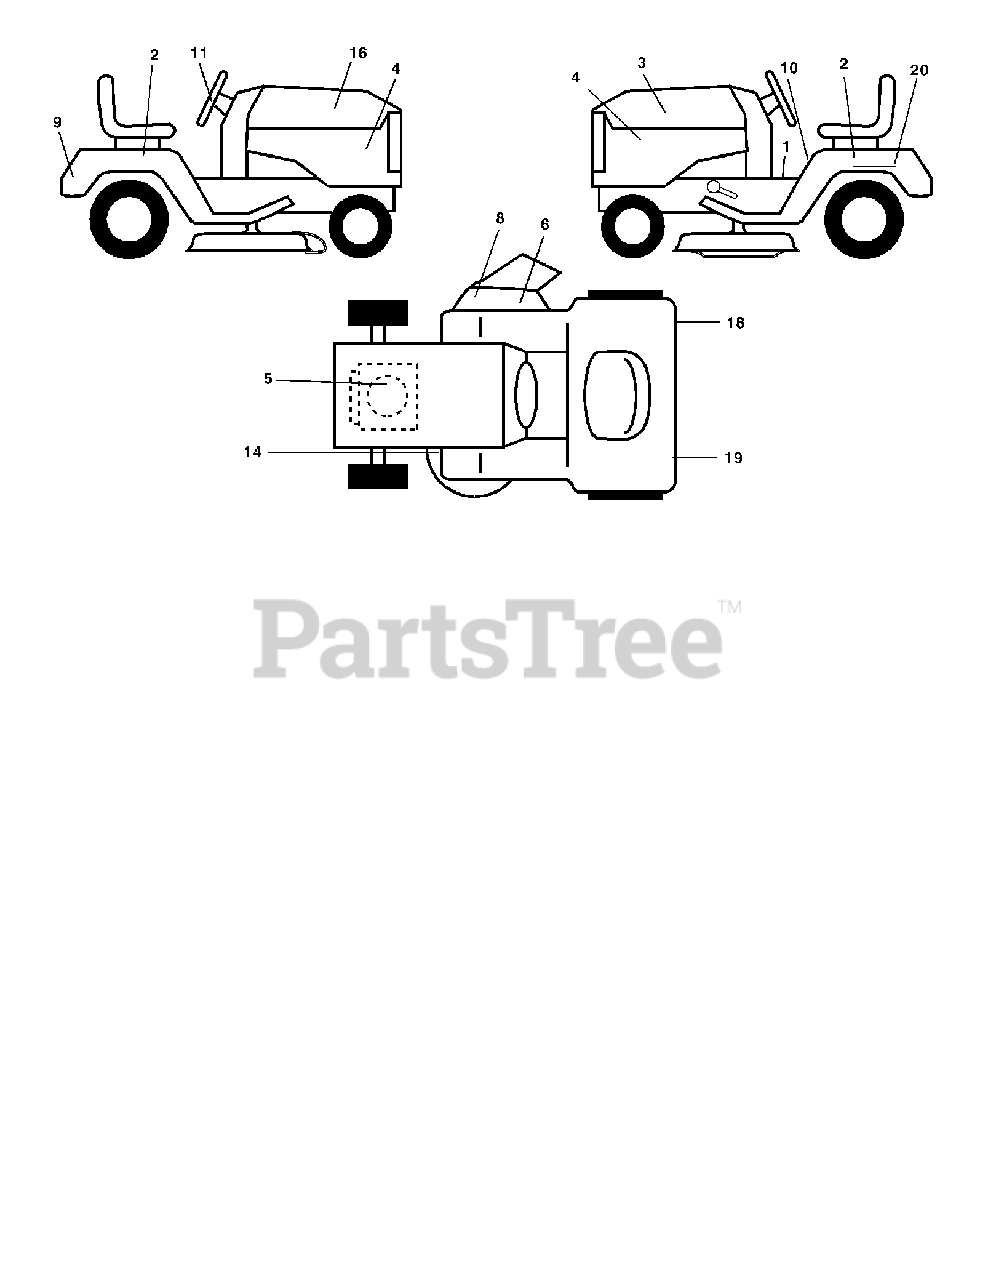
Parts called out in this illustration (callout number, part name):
1	DECAL FEND STLT OPER INST E/F
3	Husqvarna Hood Decal, LH
6	DECAL DECK B 42
8	DECAL.WARN.KEEP.HAND.AWAY
9	DECAL FENDER LOGO, POULAN
10	DECAL FENDER DANGER
11	DECAL, POULAN
14	DECAL V BELT SCHEMATIC
16	Hood Decal, RH
18	DECAL RH REFLECTOR
19	DECAL REFLECTOR LH
20	DECAL BTRY SYMBOLS
